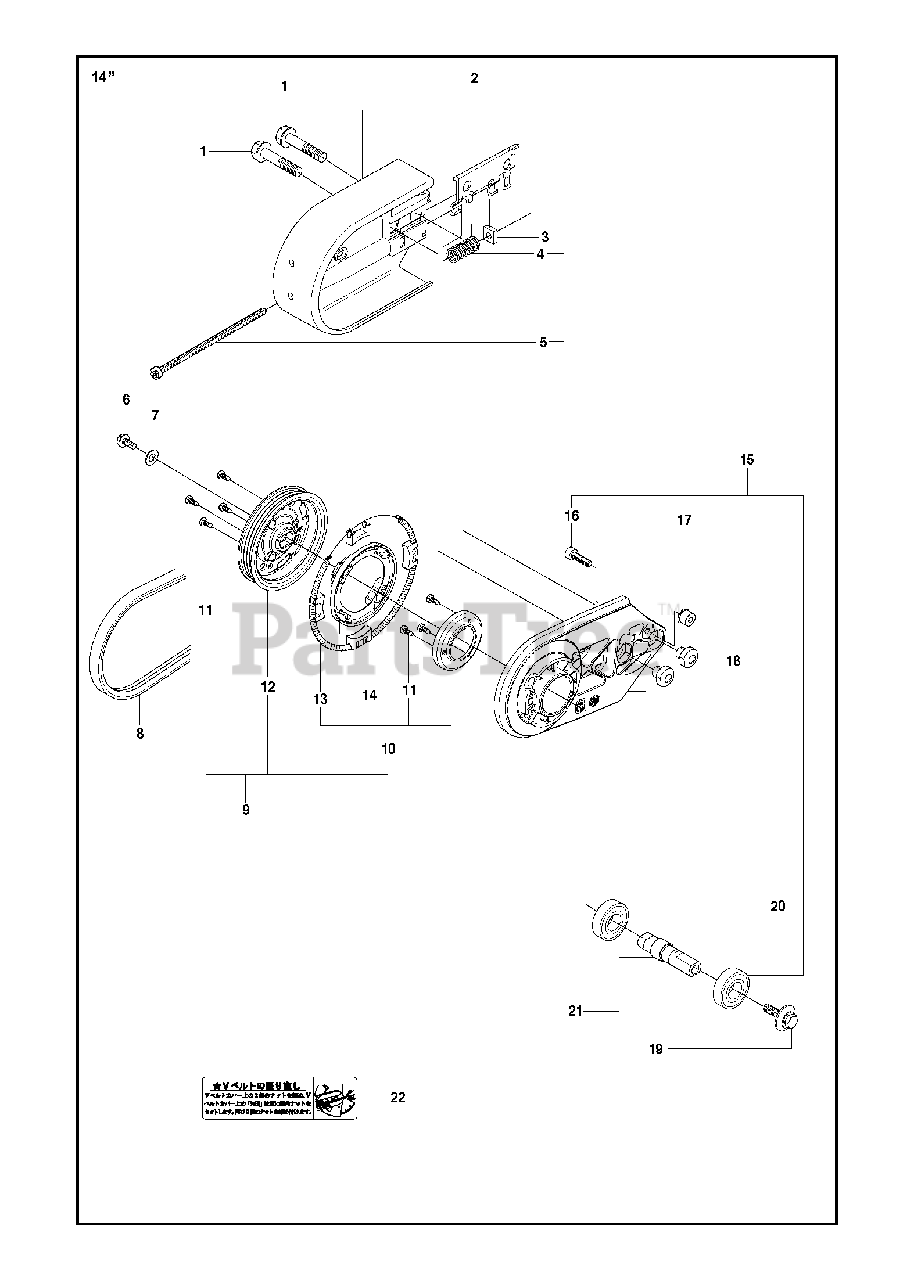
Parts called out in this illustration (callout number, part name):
4	COMPRESSION SPRING
5	SCREW CITXSCM
11	SCREW CITXPANT
15	BEARING HOUSING
16	SCREW ITXSCM
20	BALL BEARING
